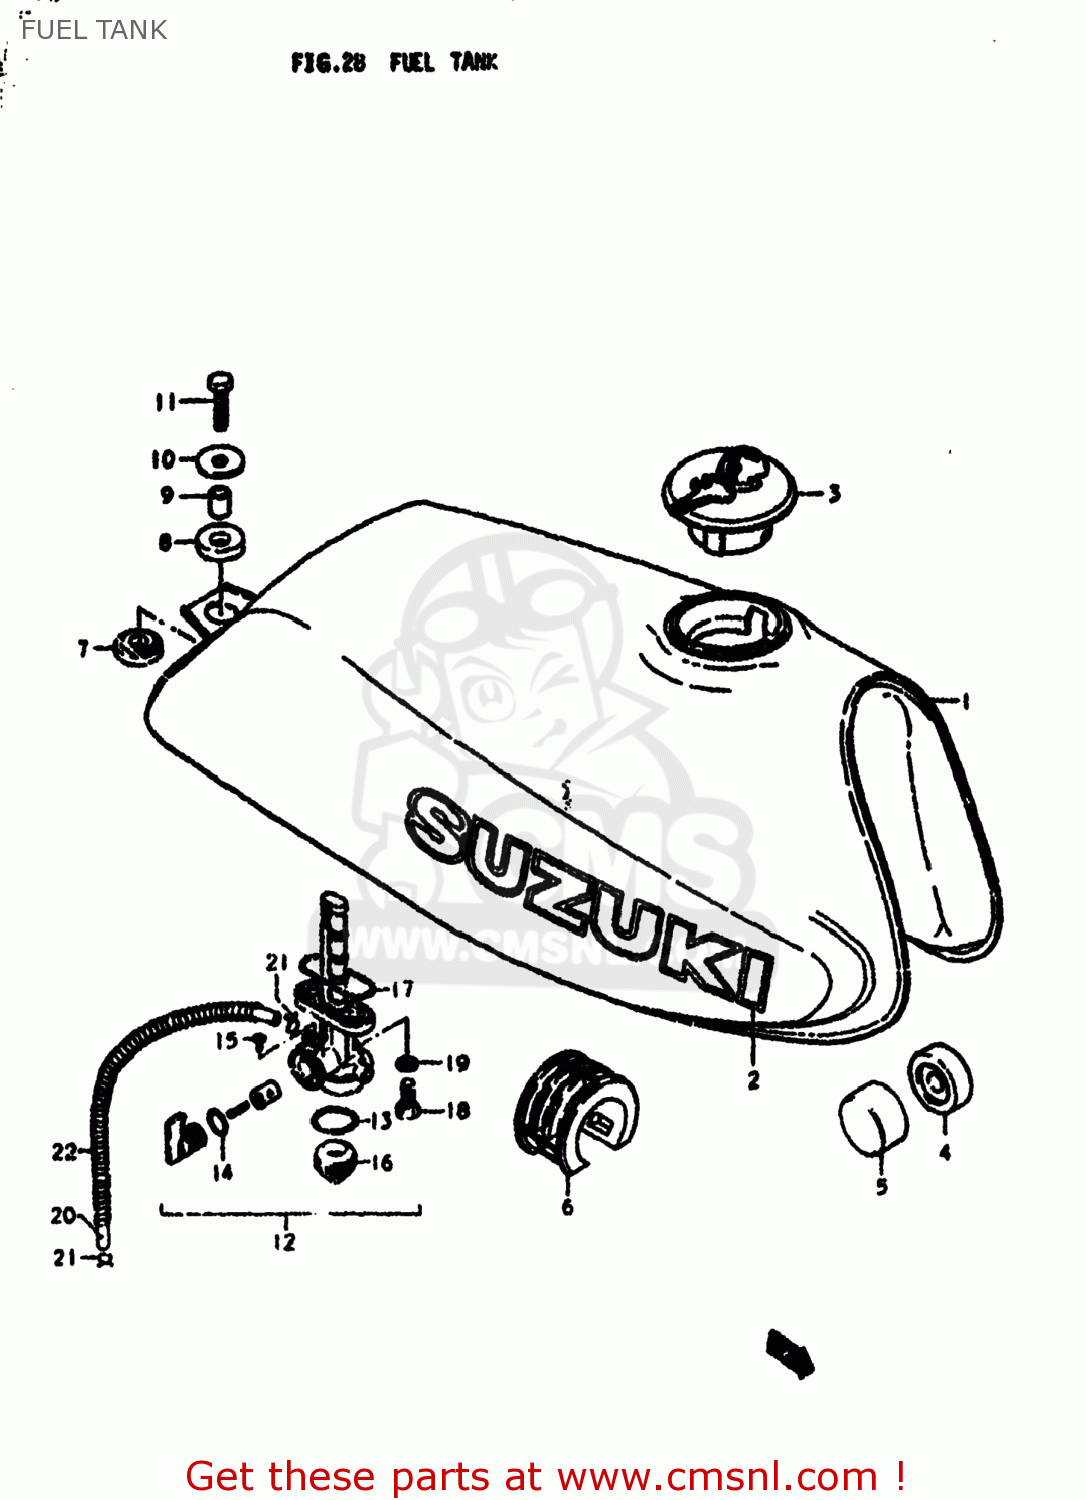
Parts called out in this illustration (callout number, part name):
1	TANK ASSEMBLY,FUEL
2	EMBLEM
3	CAP SET,FUEL TANK
4	CUSHION
5	CUSHION
6	CUSHION,FUEL TANK
7	BUSH(12X15X20)
8	CUSHION
9	SPACER (8X12X15)
10	WASHER (8.5X29X1.6)
11	BOLT
12	COCK ASSEMBLY,FUEL
13	GASKET,FILTER (NAS)
14	O-RING
15	SCREW,FUEL COCK LEVER
16	CUP,STRAINER
17	O RING,FUEL COCK
18	BOLT L:16
19	GASKET
20	HOSE
21	CLIP
22	SPRING
